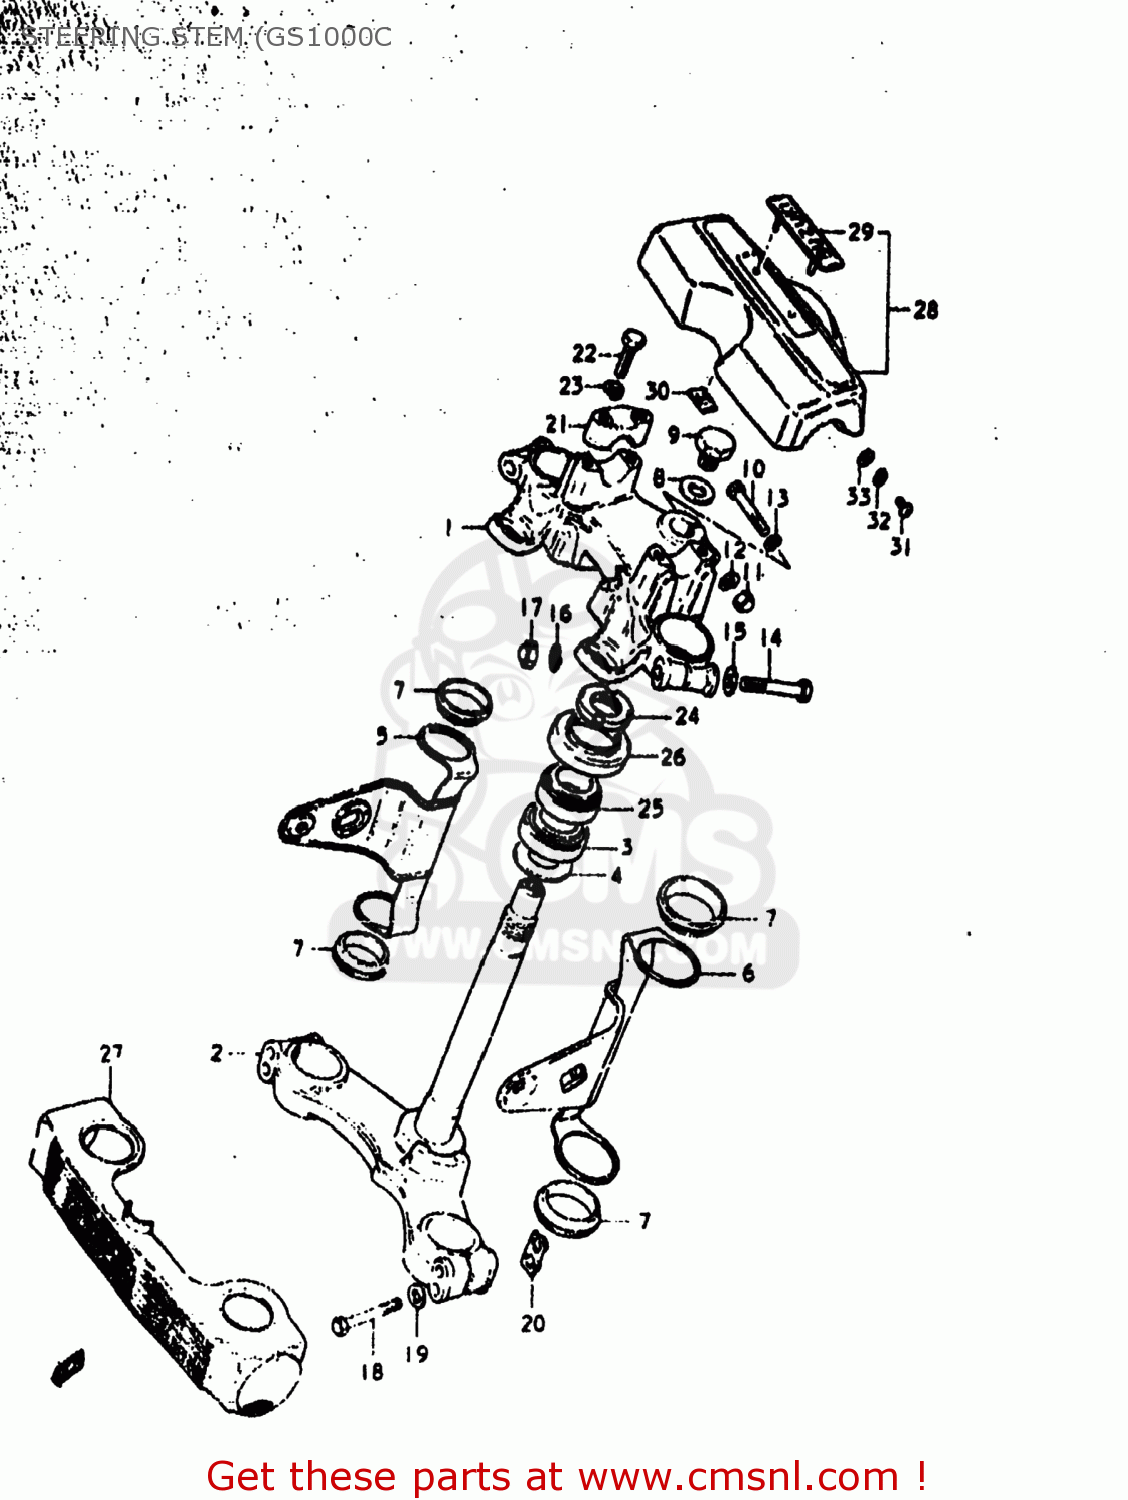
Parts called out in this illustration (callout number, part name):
1	HEAD,STEERING STEM
2	STEM,STEERING
3	BEARING
4	WASHER,THRUST
5	BRACKET,HEADLAMP,RIGHT
6	BRACKET,HEADLAMP,LEFT
7	CUSHION,HEADLAMP BRACKET
8	WASHER
9	BOLT(12X20)
10	BOLT
11	NUT
12	LOCK WASHER
13	WASHER
14	BOLT 10X55
15	WASHER
16	LOCK WASHER
17	NUT, LOWER LH
18	BOLT 8X55
19	WASHER
20	NUT,FR FORK INNER TUBE
21	HOLDER,HANDLE(BLACK)
22	BOLT
23	LOCK WASHER
24	NUT,STEERING STEM(25X44X10)
25	TAPER,ROLLER BEARING
26	DUST SEAL,STEERING,UPPER
27	COVER,FRONT FORK
28	PAD,HANDLE
29	EMBLEM
30	NUT
31	SCREW
32	LOCK WASHER
33	WASHER
